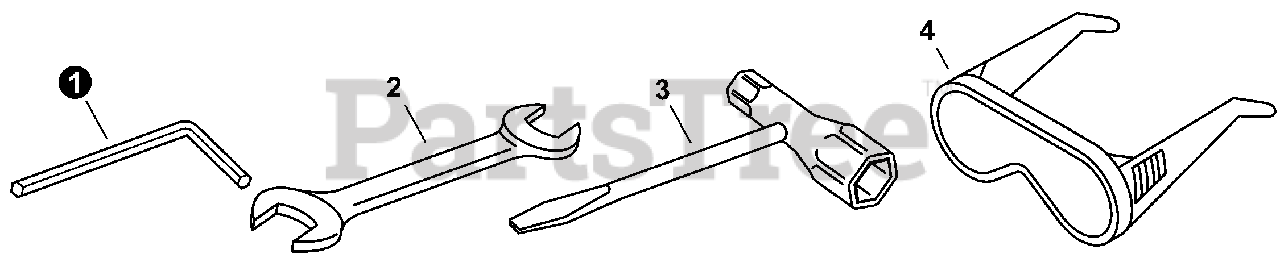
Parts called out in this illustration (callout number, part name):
1	WRENCH, ALLEN 4MM
2	SPANNER 8×10
3	T-WRENCH 17×19mm
4	GLASSES, SAFETY
